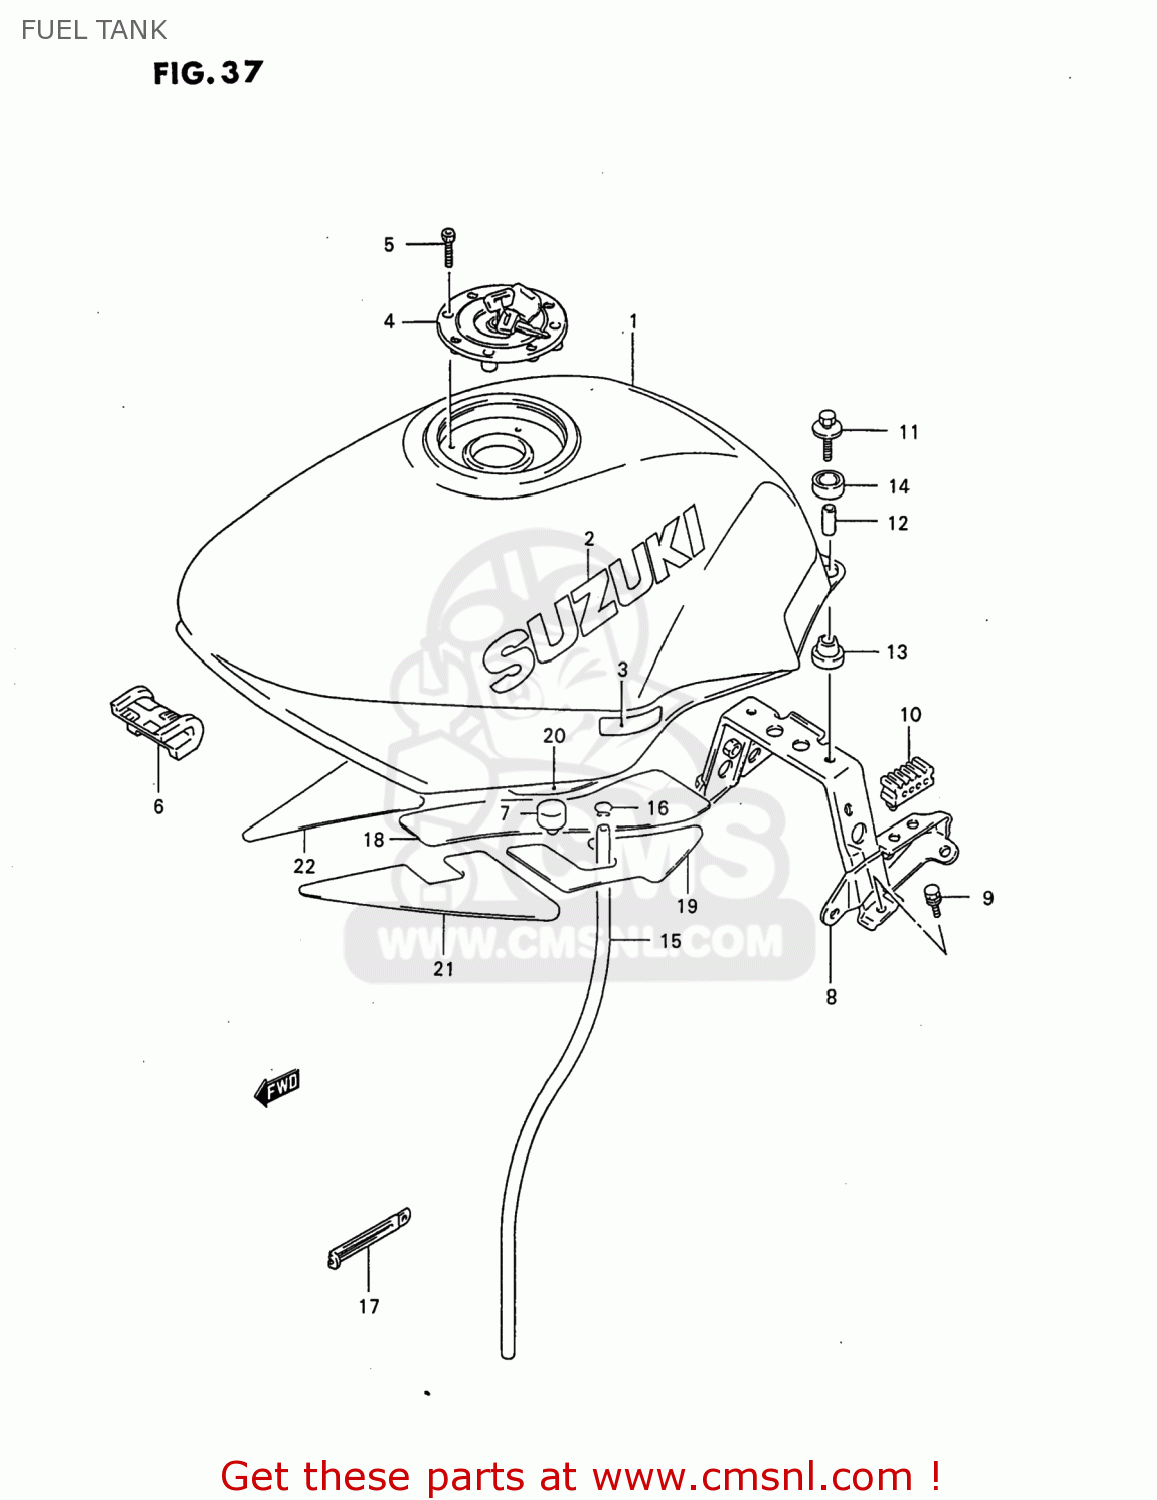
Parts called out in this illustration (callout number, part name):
1	TANK ASSEMBLY,FUEL
2	EMBLEM,FUEL TANK
3	PROTECTOR(12X40)
4	CAP SET,FUEL
5	BOLT(5X20)
6	CUSHION,FUEL TANK FR
7	CUSHION
8	BRACKET,FUEL TANK RR
9	SCREW
10	CUSHION,SEAT(40X20X15)
11	BOLT(6X30)
12	SPACER(6.5X9X18)
13	CUSHION
14	CUSHION
15	HOSE,FUEL TANK WATER DRAIN
16	CLIP
17	CLAMP(L:120 T:1.0)
18	HEATSHIELD,CTR
19	HEATSHIELD,RR,L
20	HEATSHIELD,RR,R
21	HEATSHIELD,FR,L
22	HEATSHIELD,FR,R
